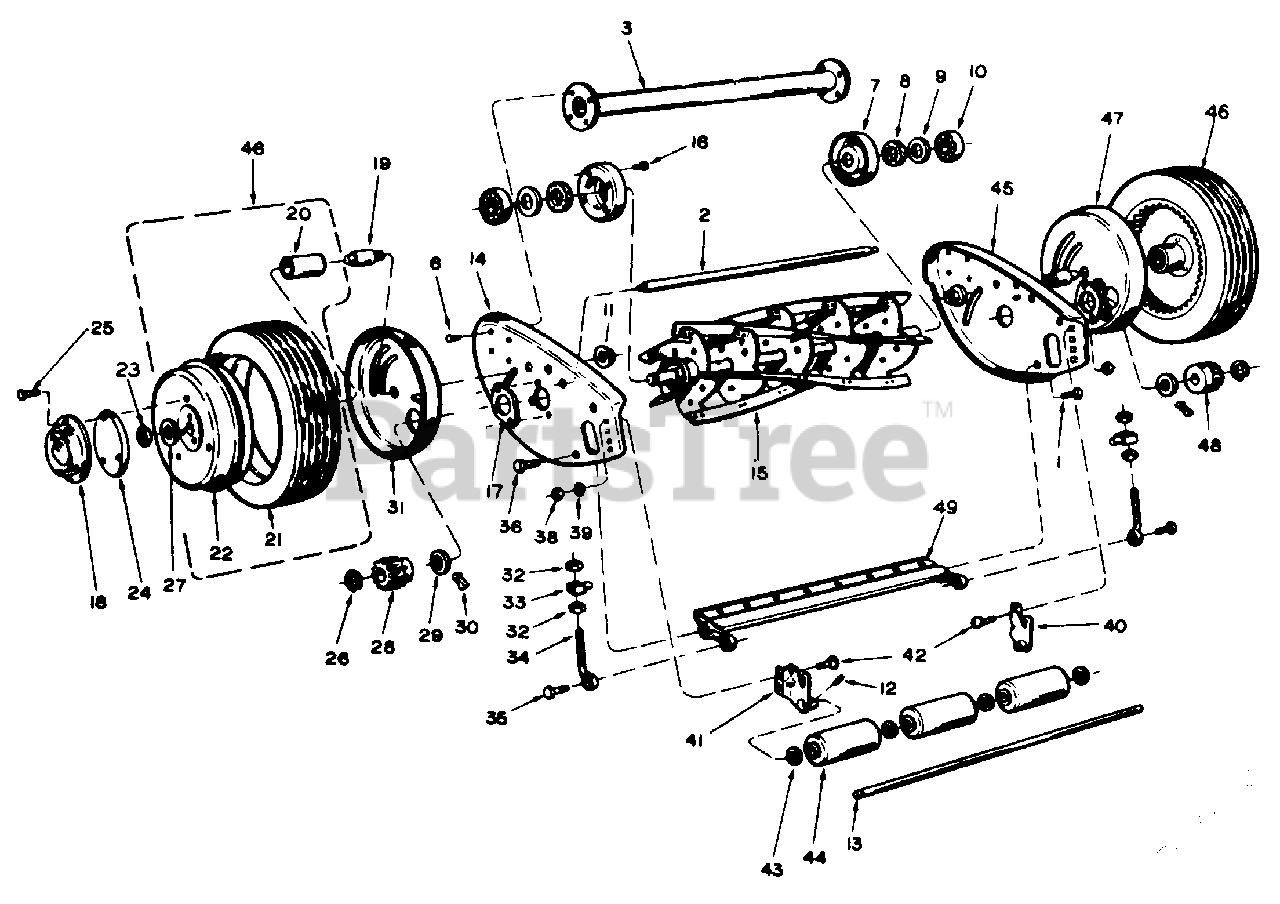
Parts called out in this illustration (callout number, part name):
2	Spacer End Plate
3	Spacer Tube Ass'y.
6	Rivet 3/16 x 3/8 Rd. Hd.*
7	Retainer
8	Felt Washer
9	Felt Retainer
10	Bearing
11	Nut- Special
12	Roll Pin
13	Roller Shaft
14	End Plate Trunnions - L.H.
15	Reel Ass'y. - 21 "
16	Rivet 3/16 x 13/32 Rd. Hd.*
17	Bearing Retainer
18	Hub Cap
20	Bearing
21	Ti re
22	Drive Wheel - Less Tire
23	Retaining Ring
24	Wheel Weight
25	Scr..#10-32 x 1 3/8 Thd. Cutting
26	Retaining Ring*
27	Washer
28	Pinion Gear- L.H.
29	Felt Washer
31	Gear Housing- L.H.
32	Hex Nut 3/8-24 Semi Fin*
33	Trunnion
34	Cutter Bar Adjusting Bolt
35	Screw- Rear
36	Screw - Front R.H. Thd.
38	Nut 5/8-18*
39	L. Wash . 5/16 " I.D.*
40	Roller Brkt. - R.H.
41	Roller Brkt. - L.H.
42	Carr. Bolt 5/16-18 x 1*
43	Washer 1/2 x 11/16*
44	Roller
45	End Plate with Trunnions - R.H.
46	Drive Wheel Ass'y. wire
47	Gear Housing- R.H.
48	Pinion Gear - R.H.
49	Cutter Bar Ass'y.
